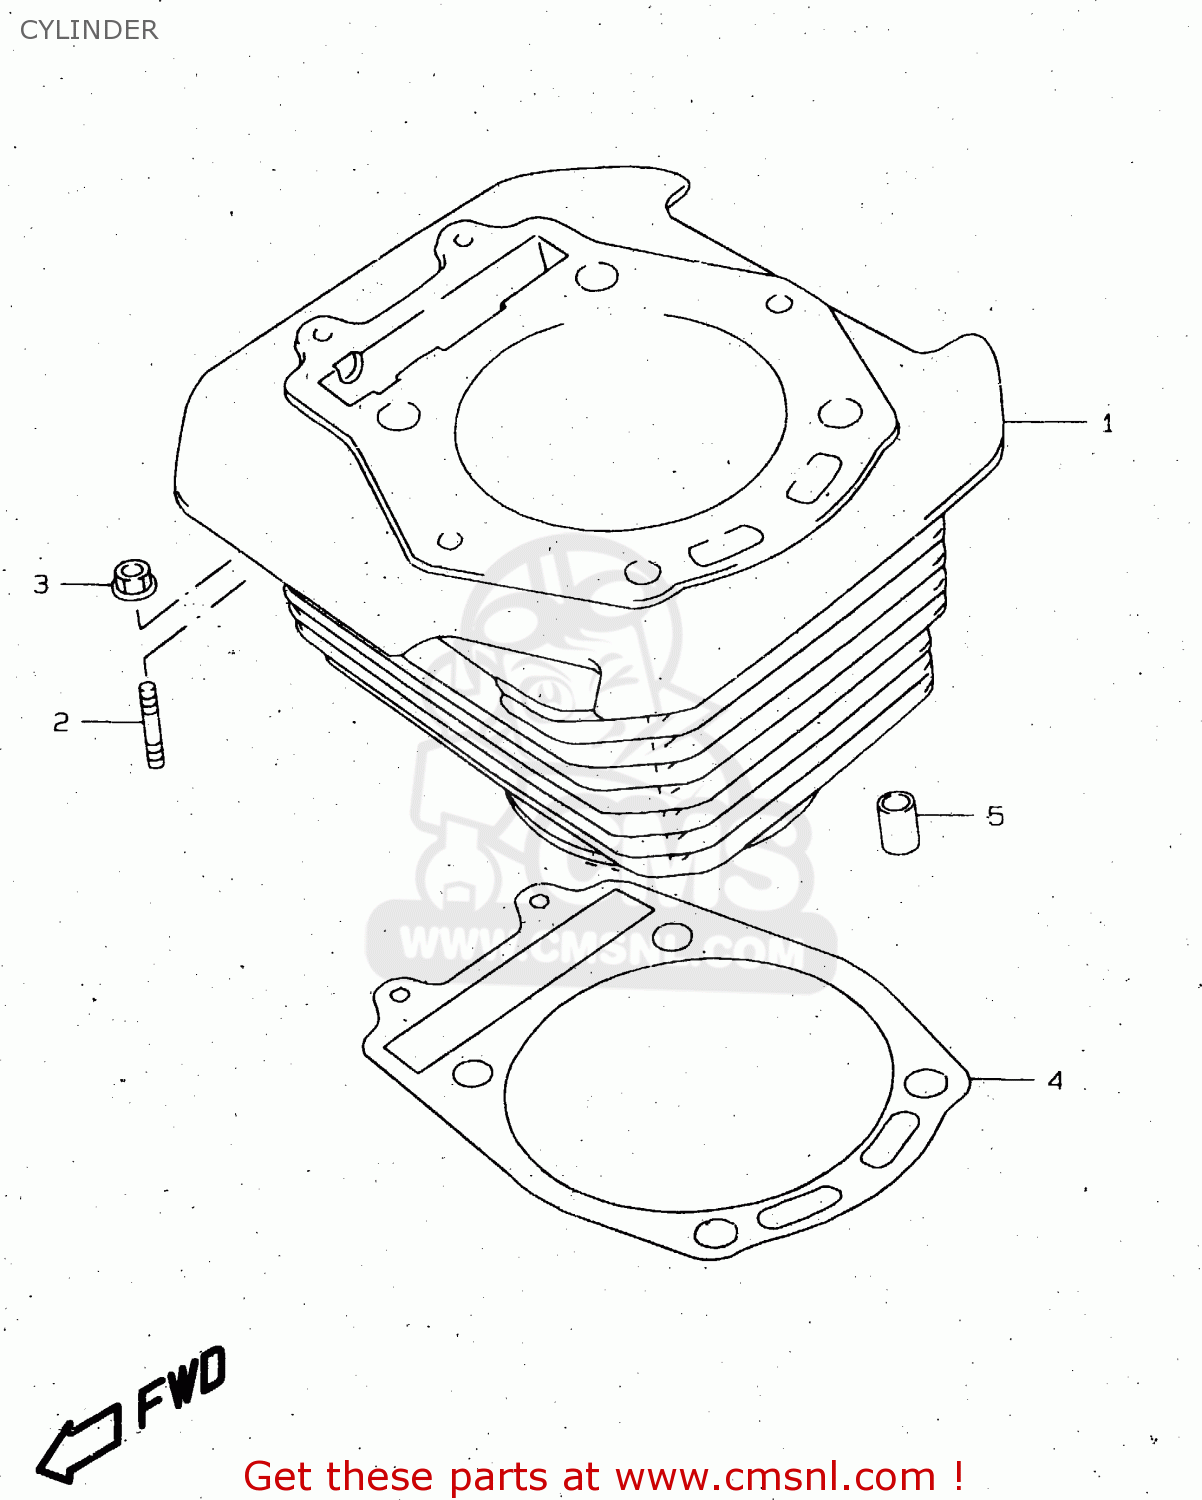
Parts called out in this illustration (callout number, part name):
1	CYLINDER
2	STUD 6X20
3	NUT
4	GASKET,CYLINDER (NAS)
5	PIN
